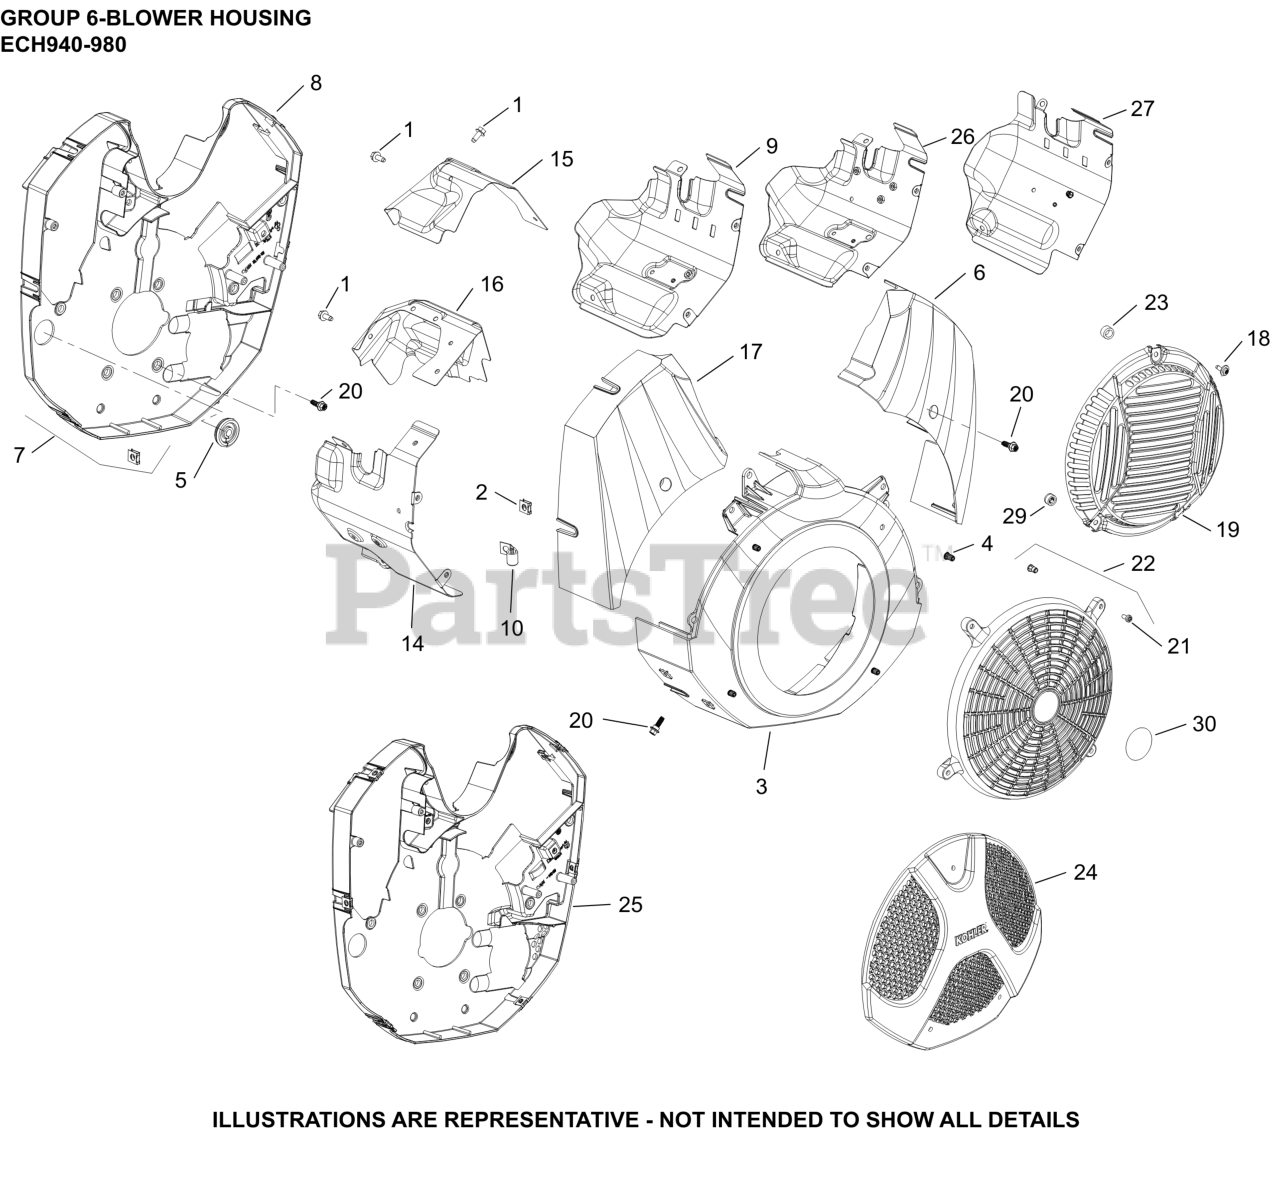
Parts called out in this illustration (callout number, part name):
1	SCREW, THREAD FORMING
2	CLIP, BAFFLE MOUNTING
3	KIT, BLOWER HOUSING
4	INSERT, THREADED (M5)
5	CGROMMET, WIRING HARNESS
6	SHROUD, #1 CYLINDER
9	BAFFLE, BARREL (#1 CYL)
14	BAFFLE, BARREL (#2 CYL)
15	BAFFLE, VALLEY #1 CYLINDER
16	BAFFLE, VALLEY #2 CYL-USE 62 063 40-S
17	SHROUD, #2 CYLINDER
18	SCREW, SEMS
19	GUARD, GRASS SCREEN (METAL)
20	SCREW, SHD THD FRM
25	SHROUD AND CLIP ASSEMBLY
